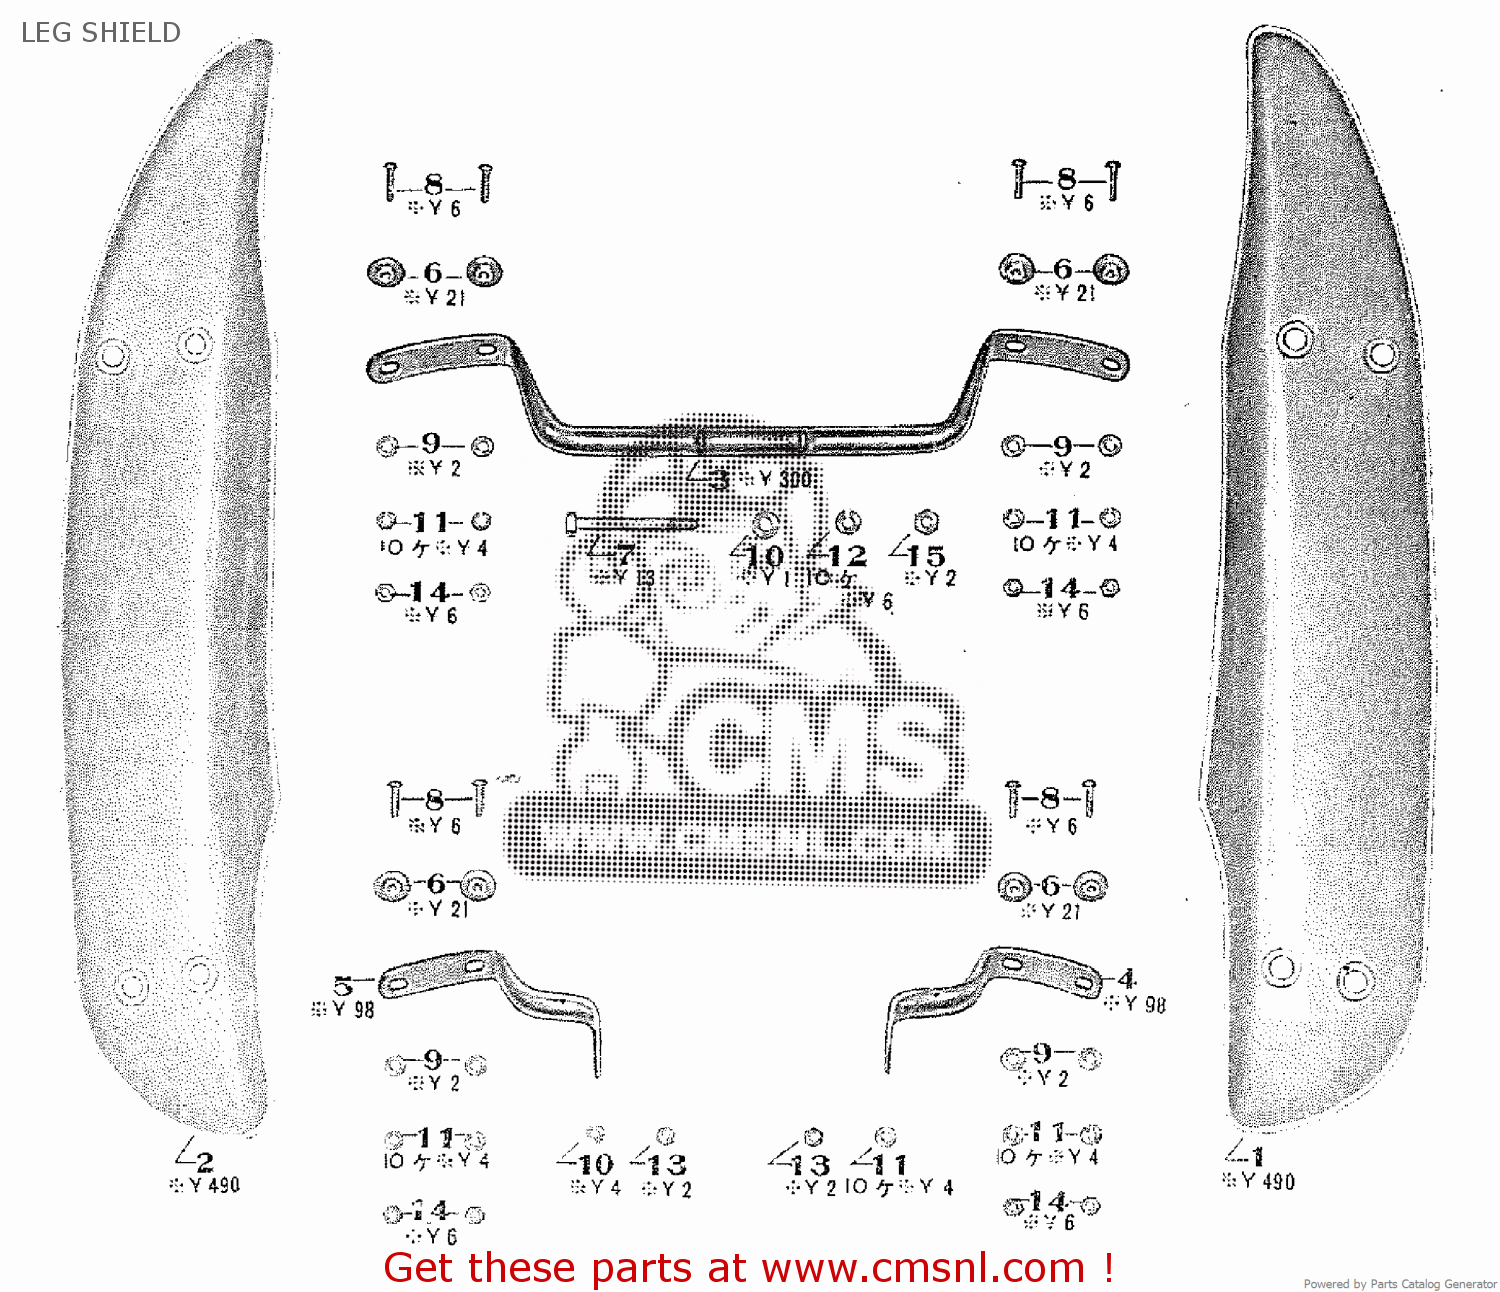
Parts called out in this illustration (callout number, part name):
1	RIGHT LEG SHIELD
2	LEFT LEG SHIELD
3	UPPER SET BAR COMP.
4	RIGHT UNDER SET BAR COMP.
5	LEFT UNDER SET BAR COMP.
6	LEG SHIELD SET WASHER
7	8X75 HEXAGON BOLT
8	6X20 CROSS SCREW
9	6MM PLANE WASHER
10	8MM PLANE WASHER
11	6MM SPRING WASHER
12	8MM SPRING WASHER
13	6MM HEXAGON NUT
14	6MM HEXAGON NUT
15	8MM HEXAGON NUT
